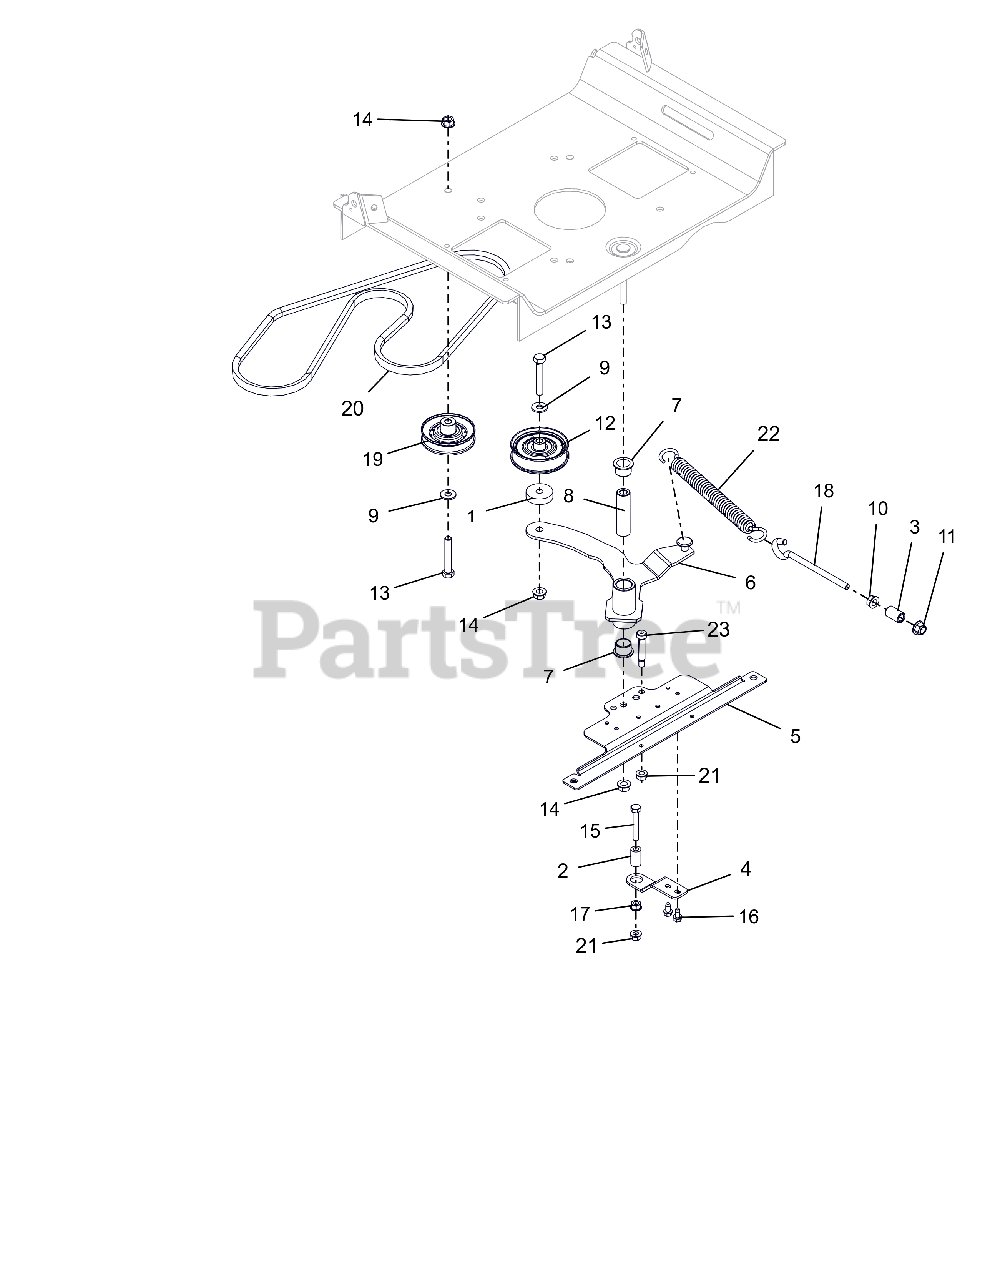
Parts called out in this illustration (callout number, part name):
1	SPACER, .39 X 1.50 X .380
2	SPACER, RUBBER 5/16 IDX1.0 LG
3	SPACER, .375X.625X.970 (PM)
4	BRKT, CLUTCH STOP
5	BRKT, DRIVE IDLER MOUNTING
6	WLDMT,GRD DRIVE IDLER ARM-LGR
7	BSHG-FLG 0.75X0.875X.625X1.125
8	BUSHING, SLEEVE .38X.750X2.78
9	WSHR,FLT .375X.875X.083 ZCC
10	NUT, SPNLK-FLG .38-16 G5 ZCC
11	NUT,NYL-FLG .38-16 GF ZCC
12	IDLER, FLAT - 3.05" X .75"
13	BLT,HEX .38-16X2.25 G5 ZCC
14	NUT-LK-TOP-FLG .38-16 ZC120
15	BLT, HEX .31-18X2.00 G5 ZCC
16	SCR-TAP .25-20X.50 HWH ZCC
17	NUT,SPNLK-FLG .31-18 G5 ZCC
18	BOLT,.38-16 X 4.25-.62 DIA EYE
19	IDLER, V-3.000 OD
20	V-BELT, A-RAW EDGE
21	NUT-LK-TOP-FLG .312-18 GF ZCC
22	SPRING, EXTENSION
23	BLT-SHLDR .38X1.5X.31-18 SLT Y
